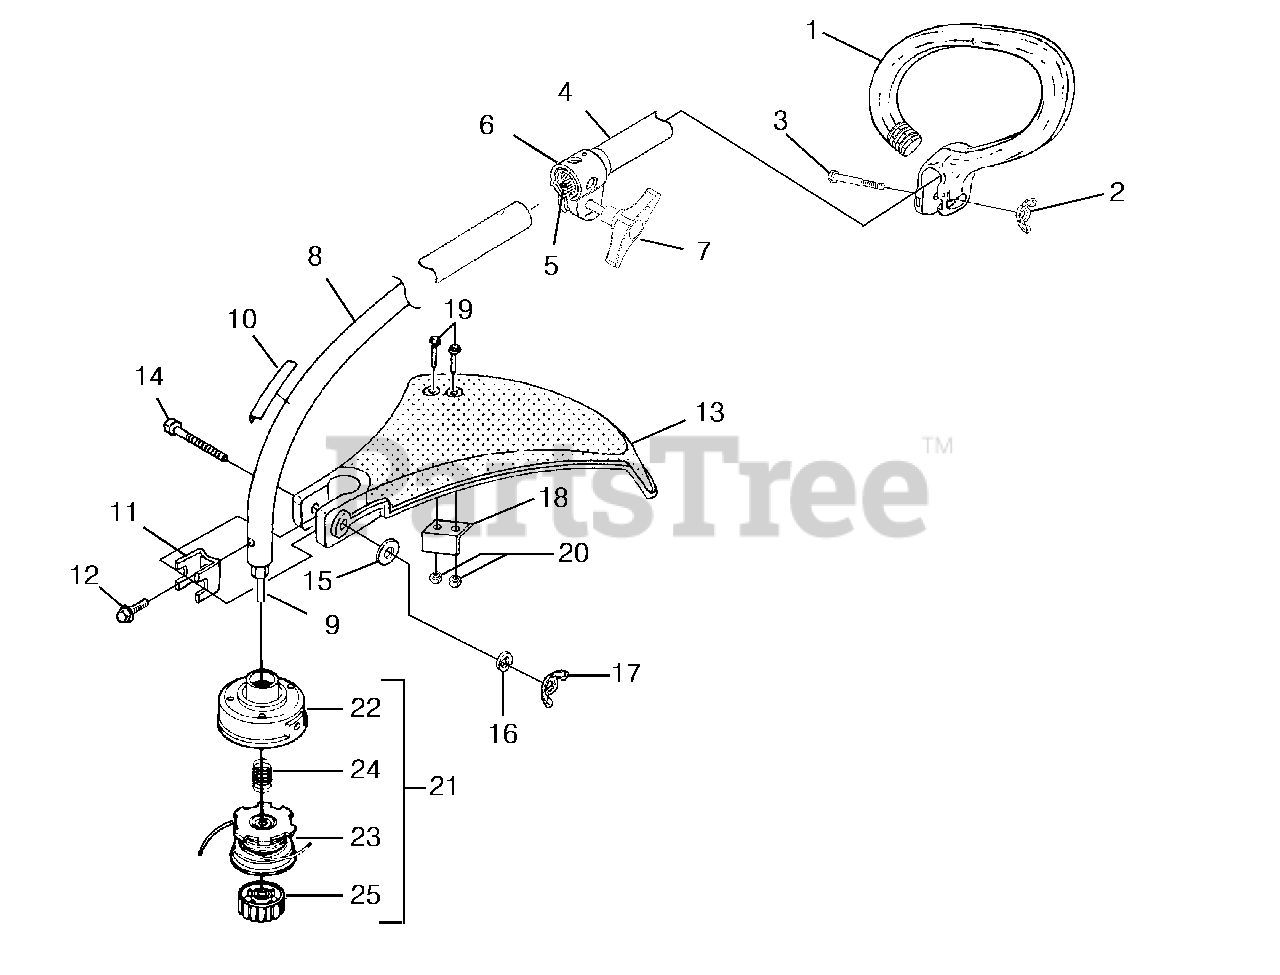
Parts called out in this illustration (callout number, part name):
1	HANDLE-Anti-Vibe
2	NUT-Wing, Washer Faced (1/4-20)
3	SCREW-Cap Hex Hd.
4	DRIVESHAFT ASSY. (Upper)
5	FLEXSHAFT
6	COUPLER ASSEMBLY
7	KNOB
8	DRIVESHAFT HOUSING (Lower)
9	SHAFT-Flex
10	DECAL-Warning
11	CLAMP
12	SCREW-Sems Hex (10-24 X 3/8")
13	DEFLECTOR & BLADE KIT (55 Deg.)
14	SCREW-Cap Hex Hd. (10-24 X 2")
15	WASHER-Flat (1/4")
16	WASHER-Lock (1/4")
17	NUT-Wing, Washer Faced (1/4-20)
18	BLADE-Cut-Off
19	SCREW-Mech. Hex Hd. (10-24 X 7/8")
20	NUT-Hex (10-24)
21	STRINGHEAD-Complete (.080")
22	HOUSING & EYELET (Dual Line)
23	SPOOL & STRING (.080")
24	SPRING-Compression
25	RETAINER-Spool (R.H. Thread, Black)
